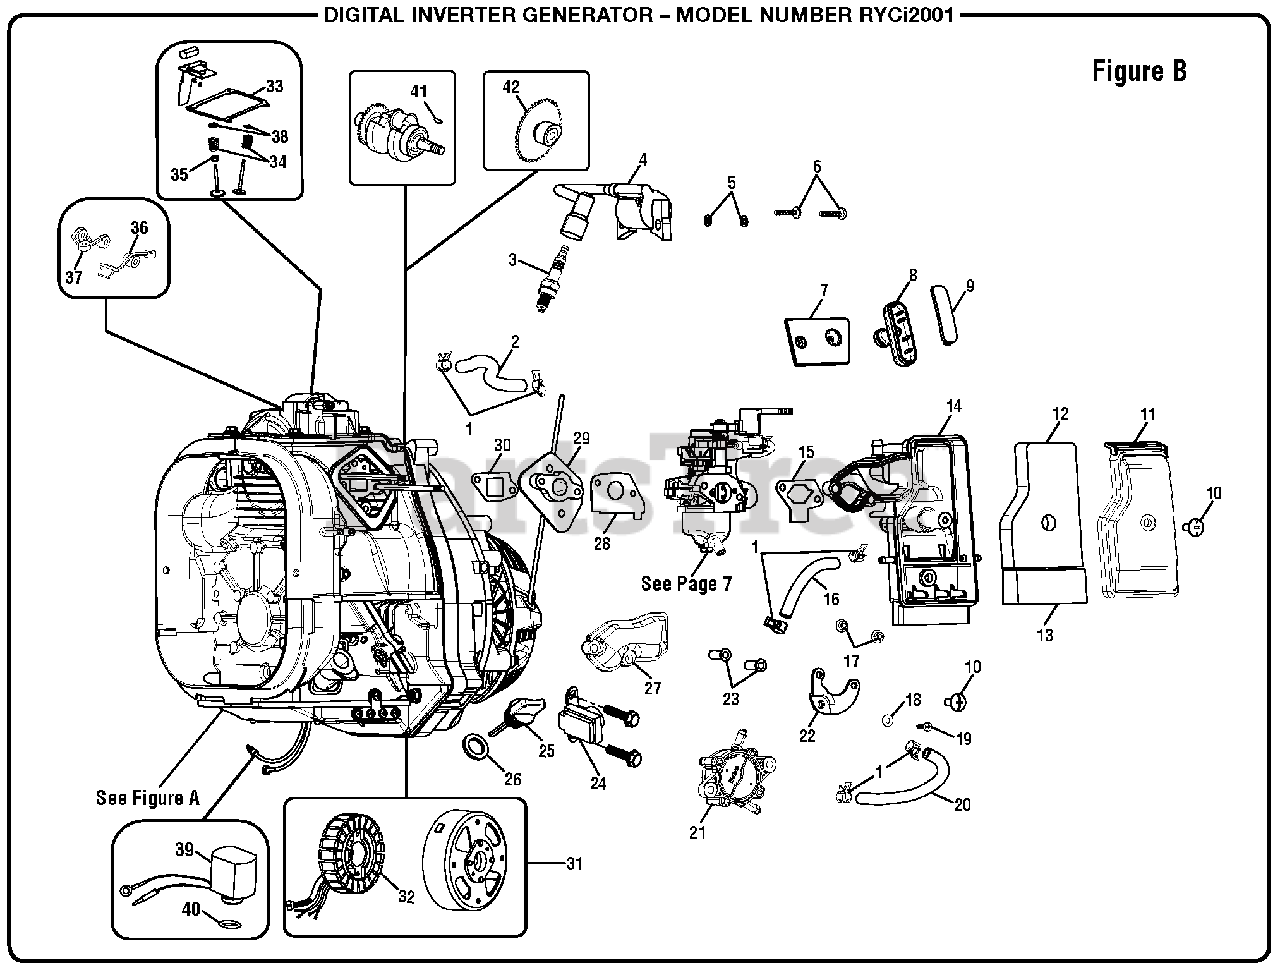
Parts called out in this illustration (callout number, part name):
1	Fuel Hose Clamp (95 mm)
2	Air Hose (3 Way Hose To Engine 180 mm)
3	Spark Plug (NHSP LD7RTS)
4	Ignition Coil
5	Washer (ID53 x OD10 x 05t)
6	Screw (M48 x 19 mm)
7	Start Rope Cover
8	Recoil Handle
9	Handle Cover
10	Screw (M8 x 16 mm, Truss Hd)
11	Air Cleaner Baffle
12	Air Cleaner Filter
13	Air Cleaner Filter
14	Air Cleaner Body
15	Intake Pipe Gasket
16	Fuel Hose (Fuel Pump To Fuel Valve, 95 mm)
17	Flange Nut (M5)
18	Washer (ID42 x OD10 x 1t)
19	Screw (M42 x 12 mm, Phillips Pan Hd)
20	Fuel Hose (Engine To Fuel Pump, 140 mm)
21	Fuel Pump
22	Fuel Pump Bracket
23	Air Cleaner Body Nesting
24	Pick-up Coil
25	Engine Oil Dipstick
26	Oil Dipstick Seal
27	Intake Pipe Top Hood
28	Carburetor Gasket
29	Intake Seat
30	Insulating Board Gasket
31	Alternator Assembly
32	Stator Assembly
33	Head Gasket
34	Valve spring
36	Intake Rocker Assembly
37	Exhaust Rocker Assembly
38	Valve Retainer
39	Oil Sensor
40	Oil Sensor Seal
41	Engine Shaft Key
42	Engine Cam
